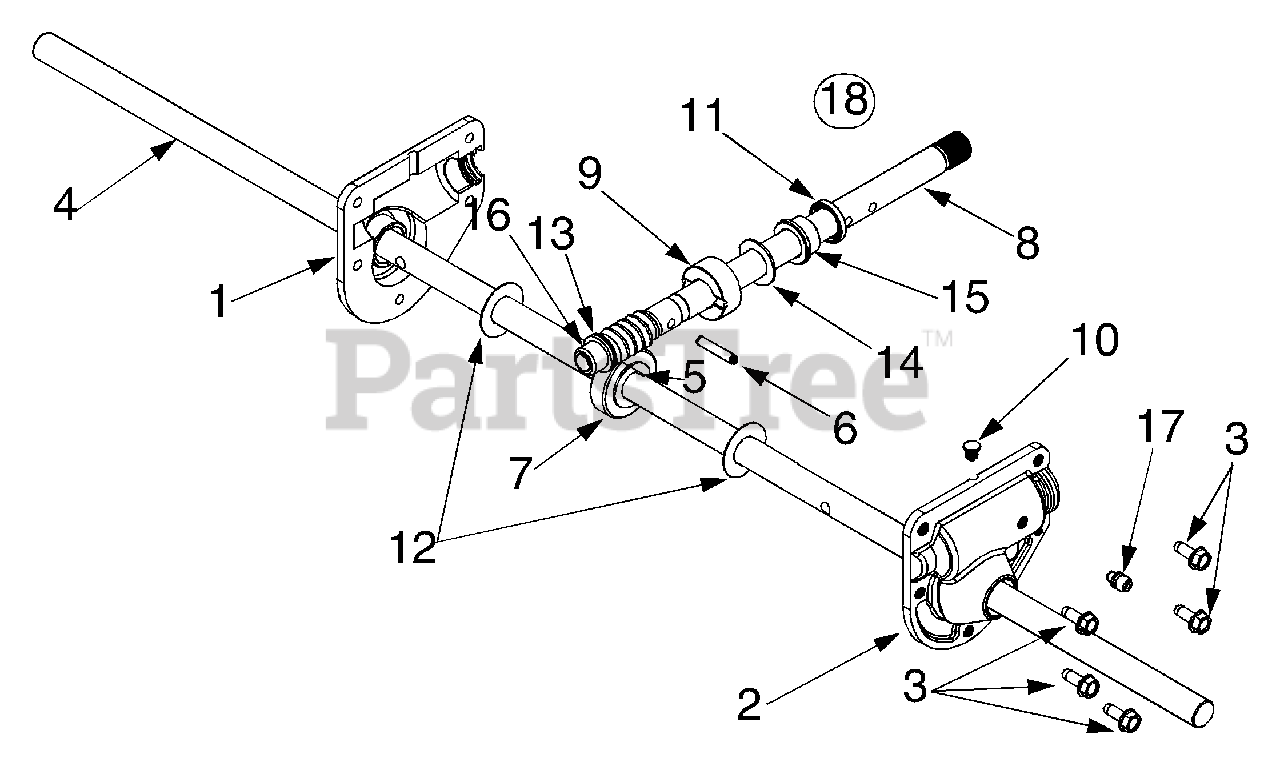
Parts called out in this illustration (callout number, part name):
1	RH Housing
2	LH Housing
3	Self Tapping Screw, 1/4-20 x.75
4	Spiral Axle
5	Hi-Pro Key
6	Spring Spiral Pin
7	Worm Gear, 20-tooth
8	Worm Shaft
9	Thrust Collar
10	Grease Plug
11	Grease Seal
12	Flat Washer
13	Flat Washer
14	Flat Washer
15	Flange Bearing
16	Flange Bearing
17	Lube Fitting
18	Gear Assembly Complete
